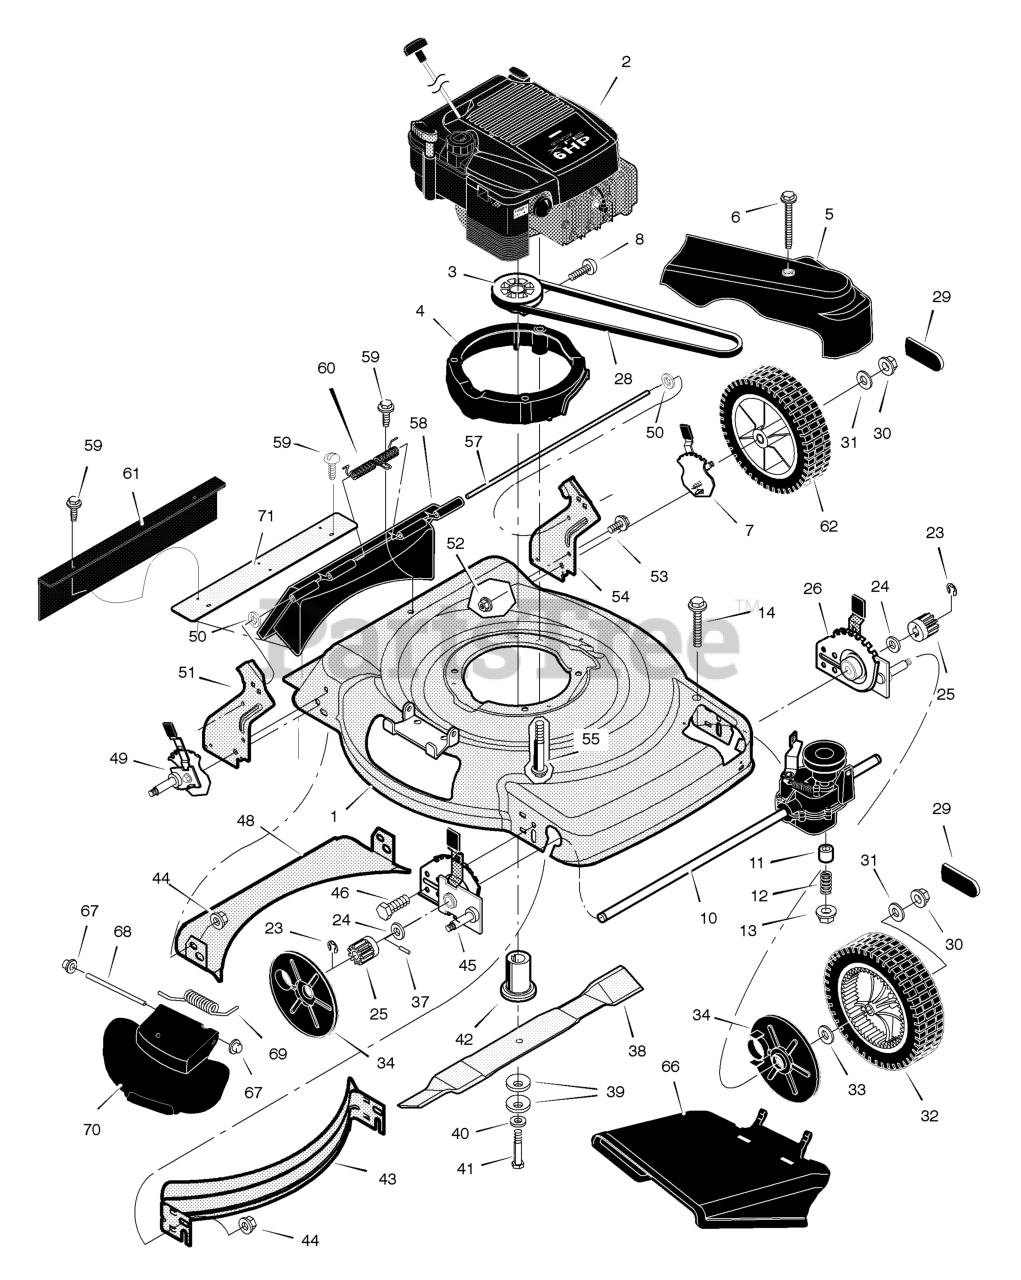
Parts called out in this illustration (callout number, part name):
2	Engine *
3	Pulley, Drive
4	Spacer, Engine
5	Cover, Belt
7	Adjuster, Left Rear Height
10	Transmission *
12	Spring, Compression
13	Nut
14	Bolt
25	Gear, Pinion
26	Adjuster, Left Front Height
29	Cap, Hub
30	Nut, Flange
31	Washer
32	Wheel & Tire, Drive
34	Cover, Dust
37	Pin, Drive
39	Washer, Belleville
42	Adapter, Blade
43	Baffle, Front
44	Nut, Flange
45	Adjuster, Right Front Height
46	Bolt
48	Baffle, Rear
49	Adjuster, Right Rear Height
50	Push Retainer
51	Bracket, Right Handle
52	Nut, Flange
53	Bolt
54	Bracket, Left Handle
55	Bolt, Engine
57	Rod, Pivot
58	Door, Rear
60	Spring
61	Guard, Rear
62	Wheel & Tire, Rear
66	Deflector, Chute
67	Push On Cap
68	Rod, Pivot
69	Spring, Torsion
70	Cover, Mulch
71	Extension, Rear
